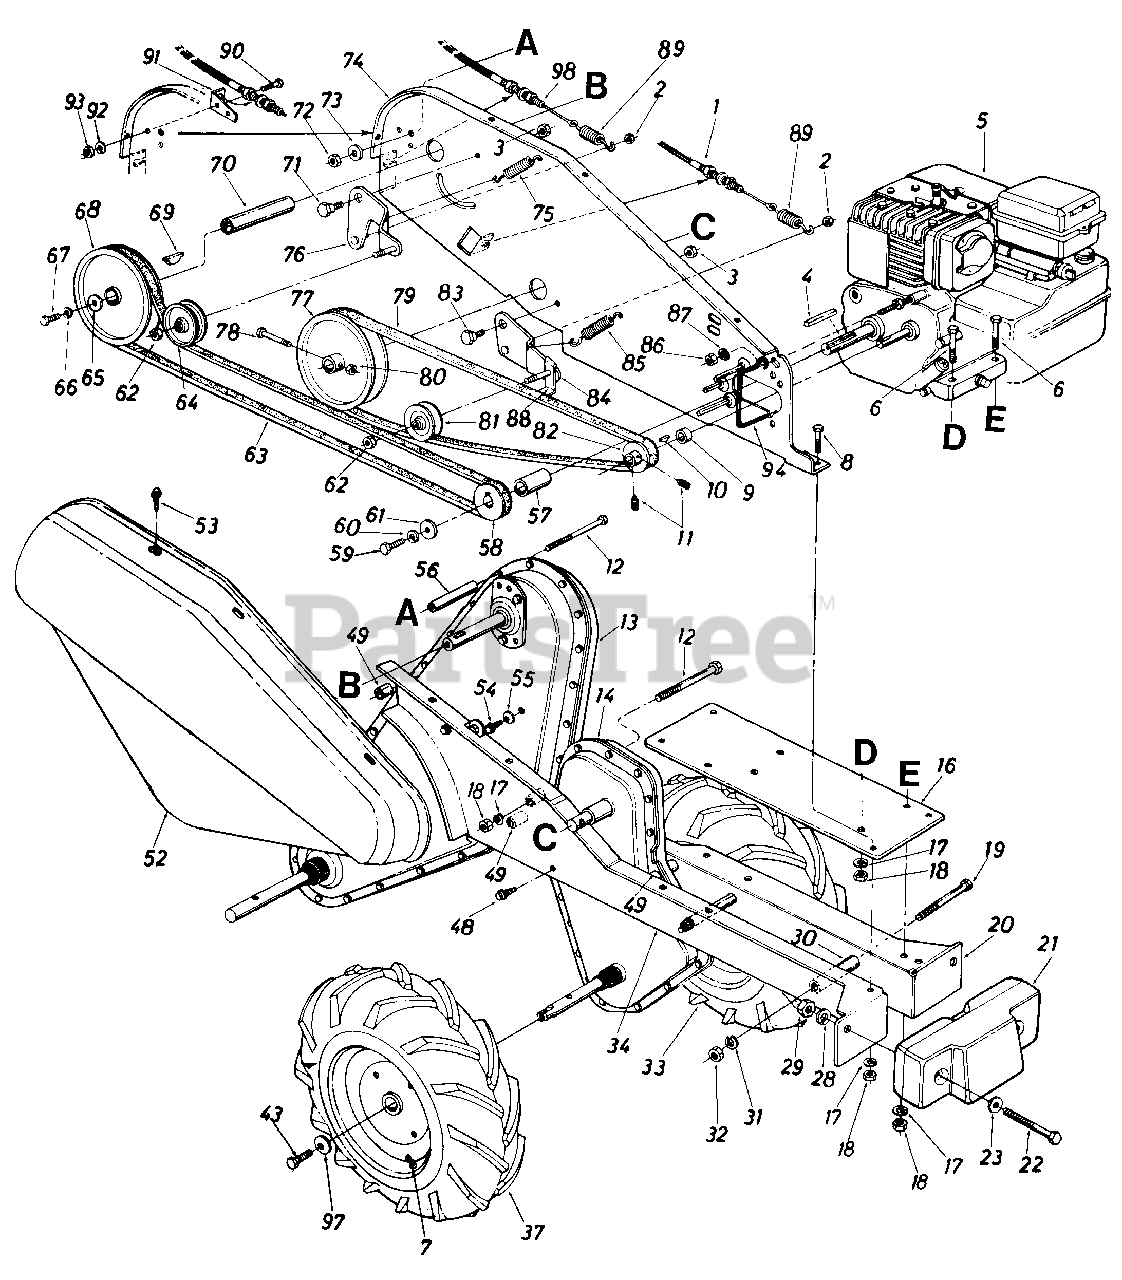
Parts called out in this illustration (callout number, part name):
1	Clutch Control Cable
2	Hex Cent. L-Nut 1/4-20 Thd.
3	Hex Cent. L-Nut 3/8-16 Thd.*
4	Sq. Key 3/16" Dia. x .75
5	Engine
6	Hex Bolt 5/16-18 x 1.50" Lg.
7	Air Valve
8	Hex Bolt 5/16-18 x .75" Lg.
9	Spacer .51" I.D. x 3/4" O.D. x.39 Lg.
10	Hi-Pro Key #5 Woodruff
11	Set Scr. 1/4-28 x .25" Lg.
12	Hex Bolt 5/16-18 x 3.0" Lg.
18	Hex Nut 5/16-18 Thd.
19	Hex Bolt 3/8-24 x 3.0n Lg.
22	Hex Bolt 1/2-13 x 4.0" Lg.
23	Fl-Wash. 1/2" I.D. x 1.0 O.D.
28	L-Wash. 1/2" I.D.
29	Hex Nut 1/2-13 Thd.
30	Spacer 3/8n I.D. x 5/8" O.D. x 2.18" Lg.
31	L-Wash. 3/8" I.D.
32	Hex Nut 3/8-24 Thd.*
33	Comp. Wheel Ass'y.-L.H.
48	Hex Wash. Self-Tap Scr. 5/16-24 x .50" Lg.
49	Spacer 5/16" I.D. x 16 Ga. x.96" Lg.
54	Hex Wash. S-Tap Scr. 1/4-20 x 3/8" Lo.
55	Bell-Wash. 1/4" I.D.
56	Spacer 3/8" I.D. x 1/2" O.D. x 2.0n Lg.
57	Spacer 3/4" I.D. x 1.12" O.D. x 1.56" Lg.
58	1/2" "V"-4L Pulley 3/4" I.D. x 2.59" O.D.
59	Hex Bolt 5/16-24 x 1.0" Lg.
60	L-Wash. 5/16" I.D.
61	Fl-Wash. 5/16" I.D. x 1.25" O.D.
62	Hex L-Nut 3/8-24 Thd.
63	"V"-Belt
64	Fl-Idler Pulley 3.75" O.D. x 3/8" I D
65	Fl-Wash. .25" I.D. x .93" O.D. x .120
66	L-Wash. 1/4" I.D.
67	Hex Bolt 1/4-28 x .75" Lg.
68	Split Pulley 6n Dia. x 5/8n I.D.
69	Hi-Pro Key
70	Spacer
71	Shld. Bolt 1/2" Dia. x .210" Lg.
72	Hex Nut 5/16-18 Thd.
73	L-Wash. 5/16" I.D.
74	Side Plate Ass'y.
75	Ext. Spring .50n O.D. x 1.55" Lg.
76	Idler Bracket Ass'y.-Tines
77	Pulley 6" Dia. x 5/8" I.D.
78	Hex Bolt 1/4-28 x 1.50" Lg.
79	"V"-Belt
80	Hex Cent. L-Nut 1/4-28 Thd.
81	"V"-Idler Pulley 2-5/8" O.D.
82	1/2n "V"-Pulley 2-1/4" O.D. x .50n I.D.
83	Shld. Bolt 1/2" Dia. x .160" Lg.
84	Idler Bracket Ass'y-Wheels
85	Ext. Spring .50" O.D. x 1.55" Lg.
86	Hex Nut 1/4-20 Thd.
87	Bell-Wash. 1/4" I.D.
88	Belt Keeper Ass'y.
89	Ext. Spring
90	Hex Bolt 5/16-18 x .75"
91	Clutch Cable Brkt.
92	LockWasher5/16n I.D.
93	Hex Nut 5/16-18 Thd.
94	Belt Keeper
97	Bell-Wash. 5/16n I.D.
98	Clutch Control Cable
